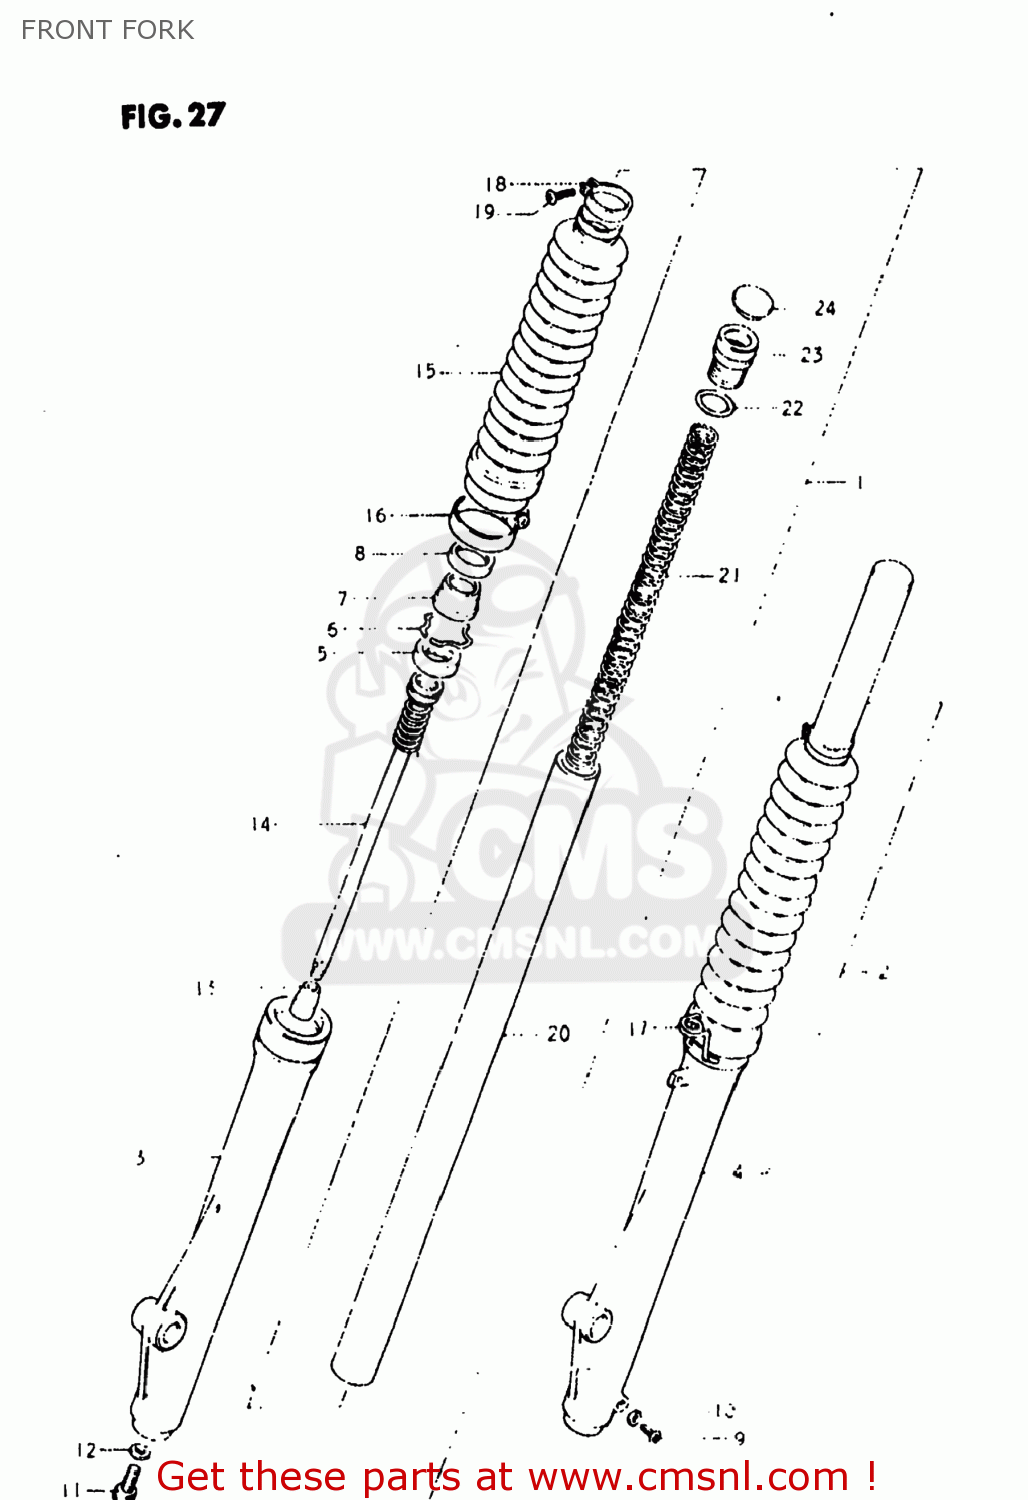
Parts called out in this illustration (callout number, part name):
1	DAMPER ASSEMBLY,RIGHT
2	DAMPER ASSEMBLY,LEFT
3	TUBE,OUTER,RIGHT
4	TUBE,OUTER,LEFT
5	OIL SEAL,FRONT FORK
6	7
7	SEAL,DUST
8	CASE,DUST SEAL
9	SCREW
10	GASKET,DRAIN,PLUG (NAS)
11	BOLT,FORK CYLINDER(10X25)
12	GASKET (NAS)
13	PIECE,OIL LOCK
14	CYLINDER,FRONT FORK
15	BOOT
16	BAND,FRONT FORK COVER
17	BAND,FRONT FORK COVER
18	BAND,BOOT
19	SCREW
20	TUBE,FORK,INNER
21	SPRING,FRONT FORK
22	O RING
23	CAP,FORK INNER TUBE
24	CAP,FRONT FORK
